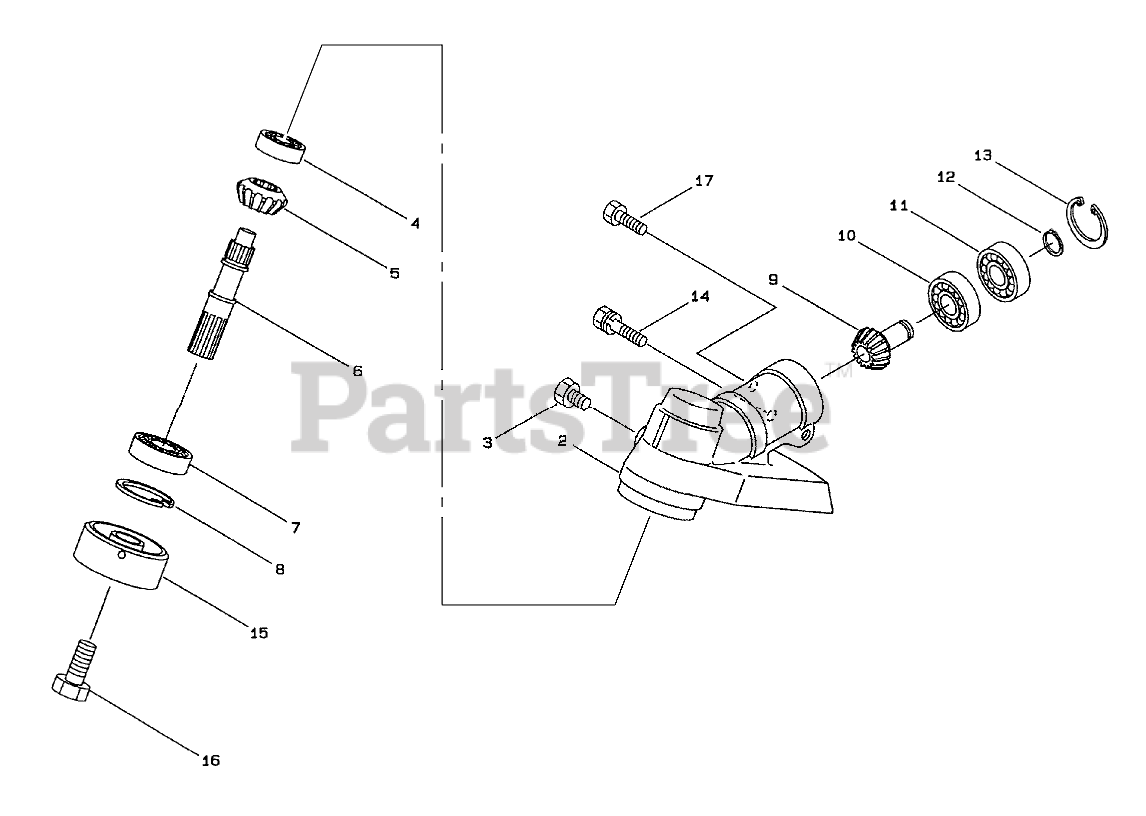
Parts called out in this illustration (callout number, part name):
2	GEARCASE
4	BEARING
6	SHAFT - BLADE
7	BEARING
8	RING - SNAP
9	GEAR - PINION
10	BEARING
11	BEARING
12	RING - SNAP
13	RING - SNAP
15	ADAPTER - BOSS
